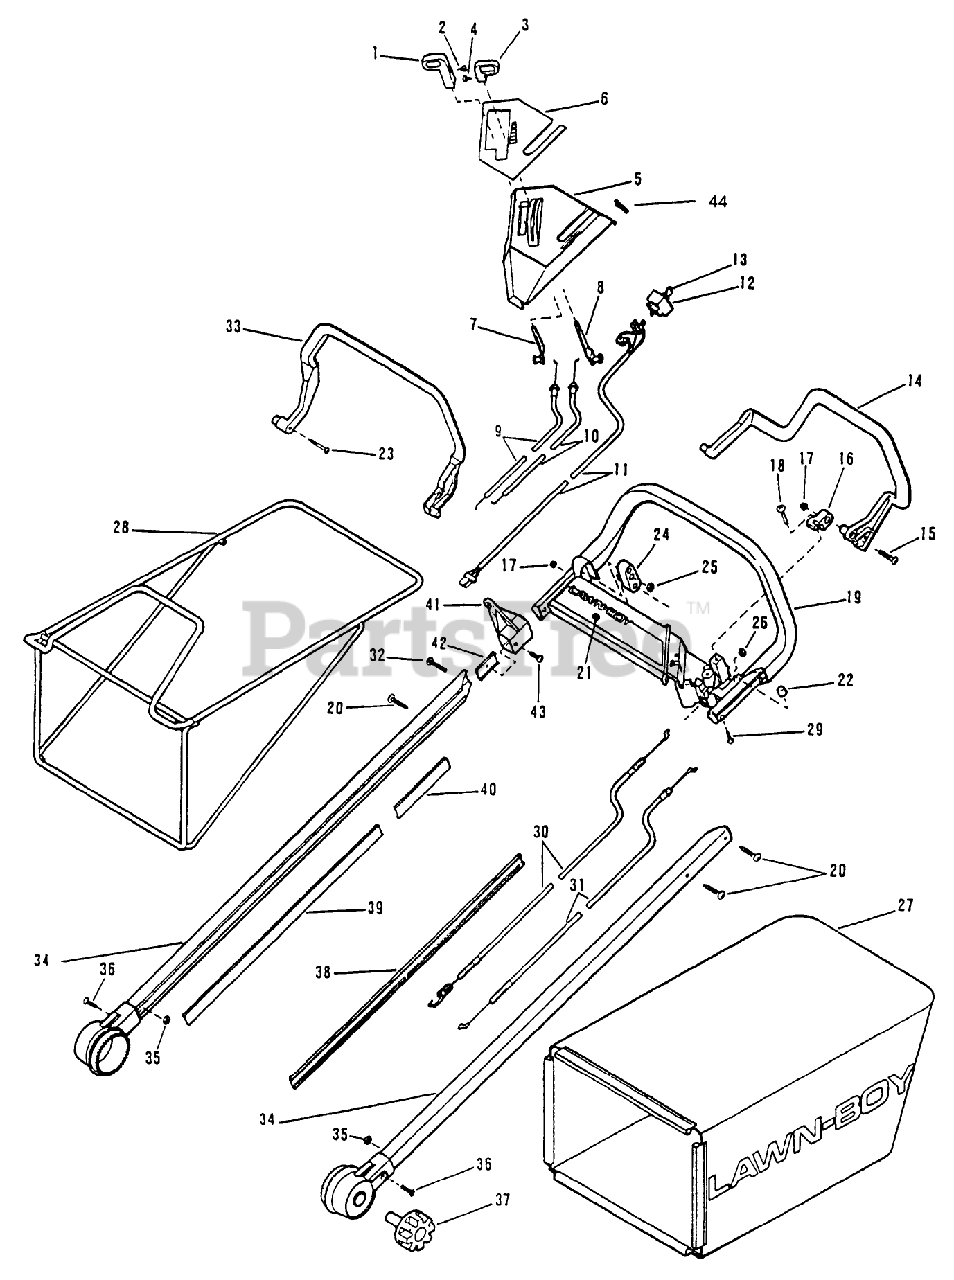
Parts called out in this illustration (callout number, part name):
1	KNOB & SCREW AY
5	UPPER CVR&DECAL AY
9	CABLE AY. WESCON
10	CABLE
14	BAIL-S.P. *
16	PIVOT BAIL PL
17	LOCKNUT FLAN
20	SCREW
24	BLOCK BAIL PL
25	LOCKNUT E
30	CABLE AY
31	CABLE ASSEMBLY
32	SCREW-TRUSS
34	HANDLE SHAFT AY
35	LOCKNUT FLAN
37	KNOB-HDLE MT.ASM*B
38	INSERT - HANDLE
42	NUT LB
